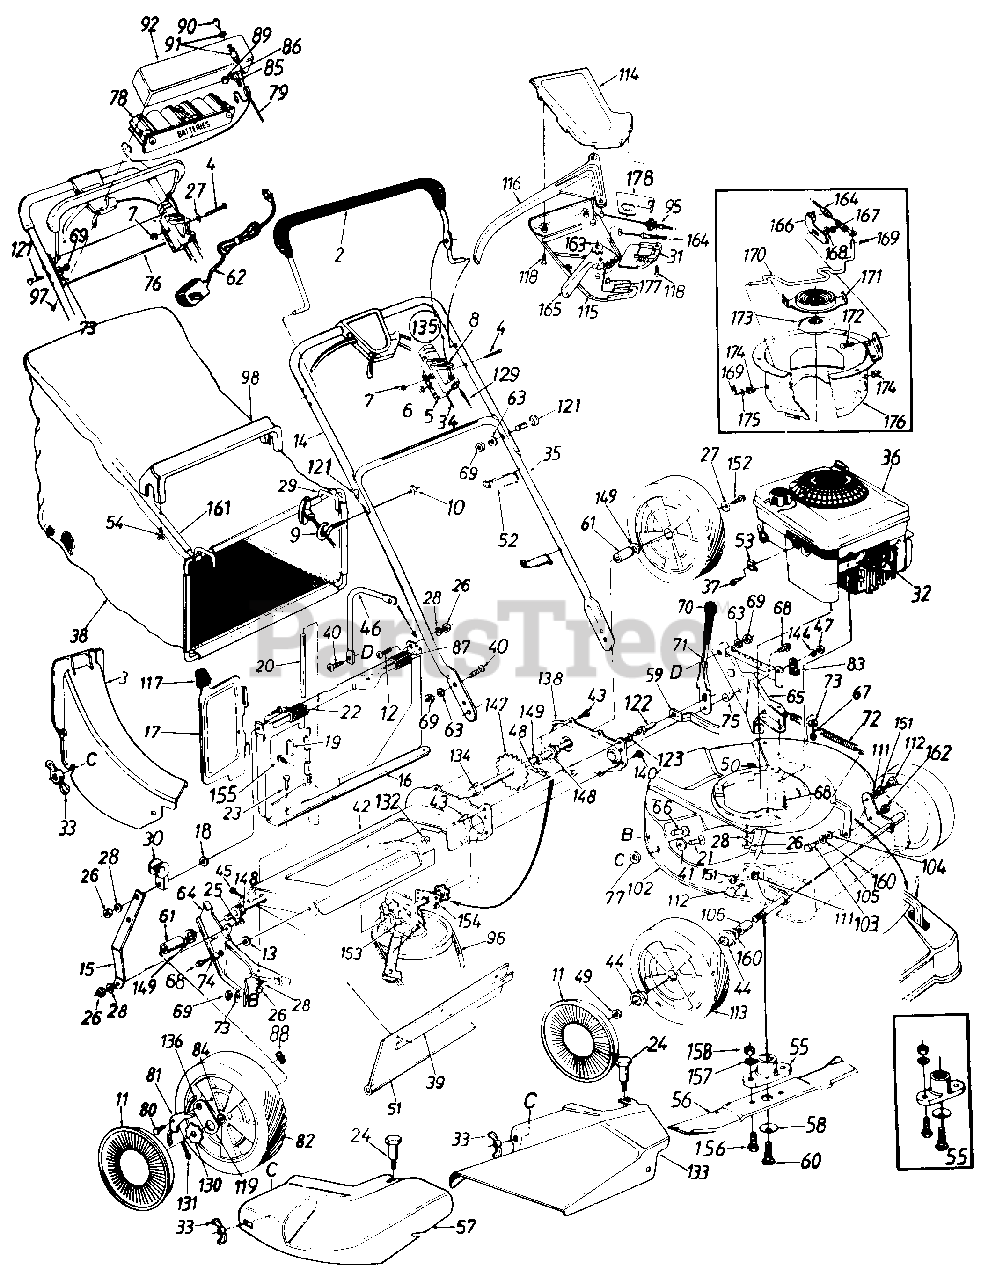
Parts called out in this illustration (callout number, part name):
2	Control Handle Ass'y
3	Rear Discharge Chute Ass'y.
4	Hex Bolt 1/4-20 x 2" Lg
5	Throttle Body
6	Spr Wash 66" I.D.
7	Hex L-Nut 1/4-20 Thd
8	Throttle Lever
9	Rope Guide Bolt
10	Hex L-Nut 1/4-20 Thd
11	Hub Cap
12	Truss Mach Scr 1/4-20 x 62" Lg
13	Fl-Wash .383" I.D. x 1" O.D.
18	Fl-Wash. 285" I.D. x 1 25" O.D.
19	Torsion Spring
20	Pivot Pin
21	Carriage Bolt 1/4-20 x 62"
22	Truss Mach Scr. 1/4-20 x 3/4" Lg
23	Hex Bolt 1/4-20 x .50" Lg
24	Shoulder Bolt 312 Dia. x 18 Lg.-Special
25	Hex Bolt 1/4-20 x 62" Lg.
26	Hex Nut 1/4-20 Thd.
27	Bell-Wash 1/4" I.D.
28	L-Wash 1/4" I.D.
30	Rope Guide
31	S.P. Control Cover
32	Spark Plug Insulator
33	Wing Nut w/Washer
34	Throttle Control Wire 61
35	Lower Handle-Painted
36	Engine
37	Hex Self-Tap Scr #10-32 x .62" Lg.
38	Grass Bag
39	Retaining Strip
40	Truss Mach Scr 5/16-18 x .75" Lg
41	Fl-Wash .344" I.D. x .62"
44	Flange Ball Bearing 1/2" I.D.
45	Hex AB-Tap Scr 1/4 x .62"
46	Catcher Panel Support Arm
47	Hex Patch L-Nut 3/8-24 Thd.
48	#48 Chain .500" Pitch x 30 Links
49	Hex L-Nut 1/2-20 Thd
51	Rear Flap 3.75" x 17.30" Lg
52	Cable Tie
53	Cable Clamp
54	Hex AB Scr #12 x 1.25" Lg
55	Blade Adapter Kit
56	21" Mulching Blade
57	Mulching Plug
58	Bell-Wash. .46" I.D.
59	Height Adj. Connecting Arm
60	Hex Bolt 7/16-20 x 1.5" L (Grade 5)
61	Spacer 513" I.D. x .703" O.D. x .69" Lg
62	Battery Charger
63	L-Wash 5/16" I.D.
64	R H Handle Wheel Brkt. Ass'y.
65	L H. Handle Wheel Brkt Ass'y
66	Carriage Bolt 5/16-18 x .62"
67	Hex Wash Hd B-Tap Scr 5/16-18
68	Hex Wash Hd. TT-Tap Sc 3/8-16
69	Hex Nut 5/16-18 Thd
71	Height Adj. Lever
72	Extension Spring .75" O.D. x 8" Lg
73	Bell-Wash. 5/16" I.D.
74	Spacer
75	Shld. Spacer 500" Dia.
78	12 Volt Battery
79	Wire Harness
80	Shld Scr. 342" Dia. x .268
81	Pawl
82	Rear Wheel Ass'y Comp
84	Bearing 1/2" I.D.
85	Plug
86	Fuse Holder
87	Panel Clip
88	Weld L-Nut 1/4-20 Thd.
89	Fuse 7-1/2 Amp
90	Key
91	Key Switch
92	Upper Battery Tray
95	S P. Cable
96	"V"-Belt
97	Hex AB-Tap Scr. 1" Lg
98	Bag Handle
102	21" Deck Ass'y.
103	Shld. Bolt 5" Dia. x .295
104	Bell-Wash. .515" I.D x 1.0 O.D.
105	Front Axle Ass'y.
106	Sleeve .526" I.D. x .690 O.D. x .880" Lg.
111	Intern. L-Wash. 3/8 I.D.
112	Shld. Bolt .575" Dia x .42
113	Front Wheel Ass'y Comp
114	Self-Propelled Control Cover
115	Self-Propelled Control Cover
116	Control Lever
117	Door Grip
118	Fl-"C"-Sunk Hd. Tap Sc #10 x .75" Lg.
119	Pawl Plate
121	Curved Carr Bolt 5/16-18 x 1.38" Lg
122	Shld. Pin 3/8-24 x 1.43" Lg
123	L-Wash. 3/8" I.D.
129	Control Cable 47" Lg
130	Ratchet Wheel 1.62" O.D.
131	Cotter Pin 1/8" Dia. x 1.00" Lg
132	Hex Jam Nut 3/8-24 Thd
133	Side Chute Deflector Ass'y
134	Hex Flange Bearing
135	Throttle Box Comp.
136	Spring-Nylon
144	Fl-Wash .385" I.D. x .87"
147	Rear Shaft Ass'y. 21.94" Lg.
148	Hex Flange Bearing .506" I.D. Plastic
149	Fl-Wash. .531" I.D. x .930"
151	Flanged Nyliner Brg.
152	Hex Bolt 1/4-20 x .62" Lg (Grade 5)
153	Transmission Comp.
154	Hex Bearing Cup
155	Hex B-Tap Scr. #10 x .38
156	Hex Scr 3/8-24 x 1.0" Lg
157	L-Wash 3/8" I.D.
158	Hex Nut 3/8-24 Thd
160	Fl-Wash .51 "I.D. x .75" O.D.
162	Hex Jam Nut 3/8-16 Thd
163	3 Tooth Rack Gear Insert
164	Spd Control Cable-50" Lg
165	6-Spd. Shift Lever
168	Hex Cent L-Nut 1/4-20 Thd
169	Cot-Pin 3/32" Dia x .75" Lg
170	Shift Rod
171	Movable Pulley Half Ass'y
172	Carr Bolt 1/4-20 x .50" Lg
173	Splined Pulley Half
174	Flanged Bushing
175	Fl-Wash .328" I.D. x .68" O.D.
176	Cable Mtg Brkt Ass'y
177	Shift Lever Spring
178	6-Speed Rack Cable Brkt
